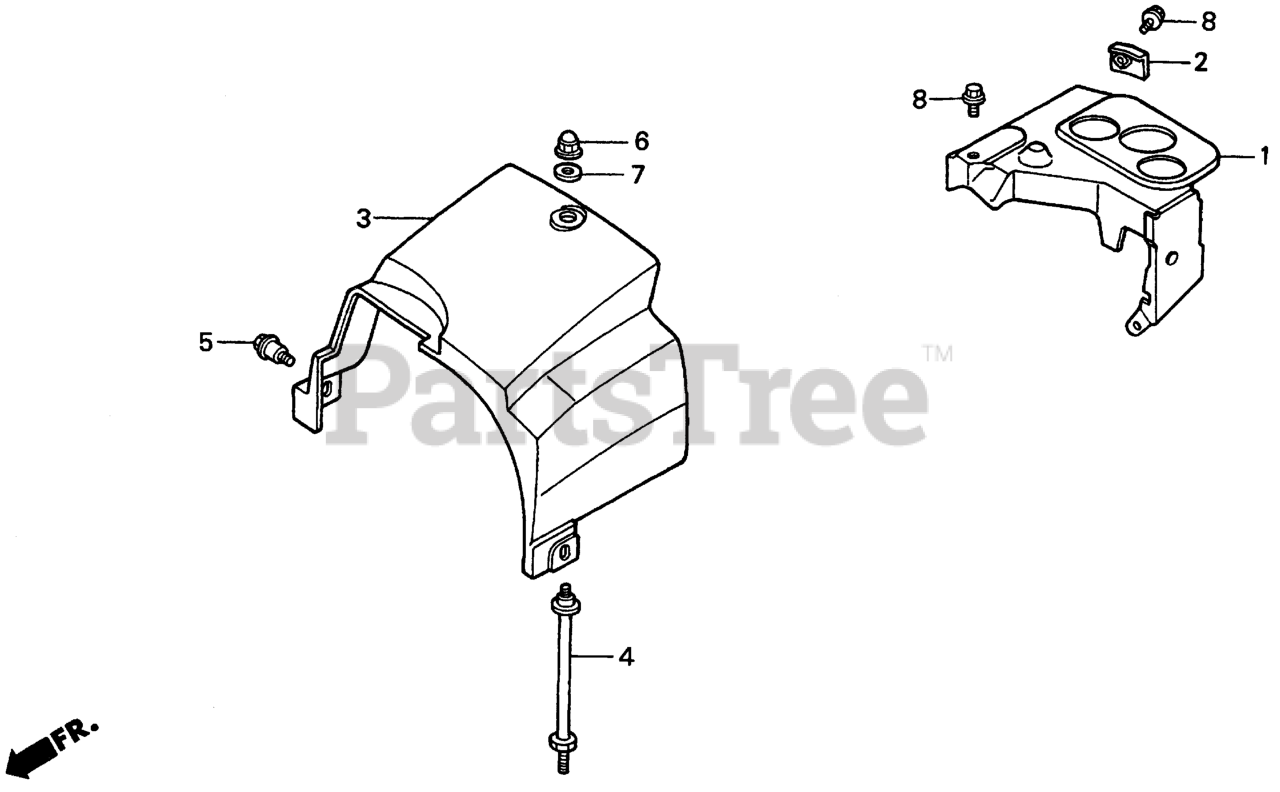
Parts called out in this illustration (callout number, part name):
1	COVER, ENG CONT
2	STOPPER, THROTTLE LEVER
3	COVER, TOP *R280*
4	BOLT, TOP COVER SETTING
5	BOLT, FLANGE (6MM)
6	NUT, CAP (6MM)
7	WASHER, PLAIN (6X16)
8	BOLT, FLANGE (6X10)
